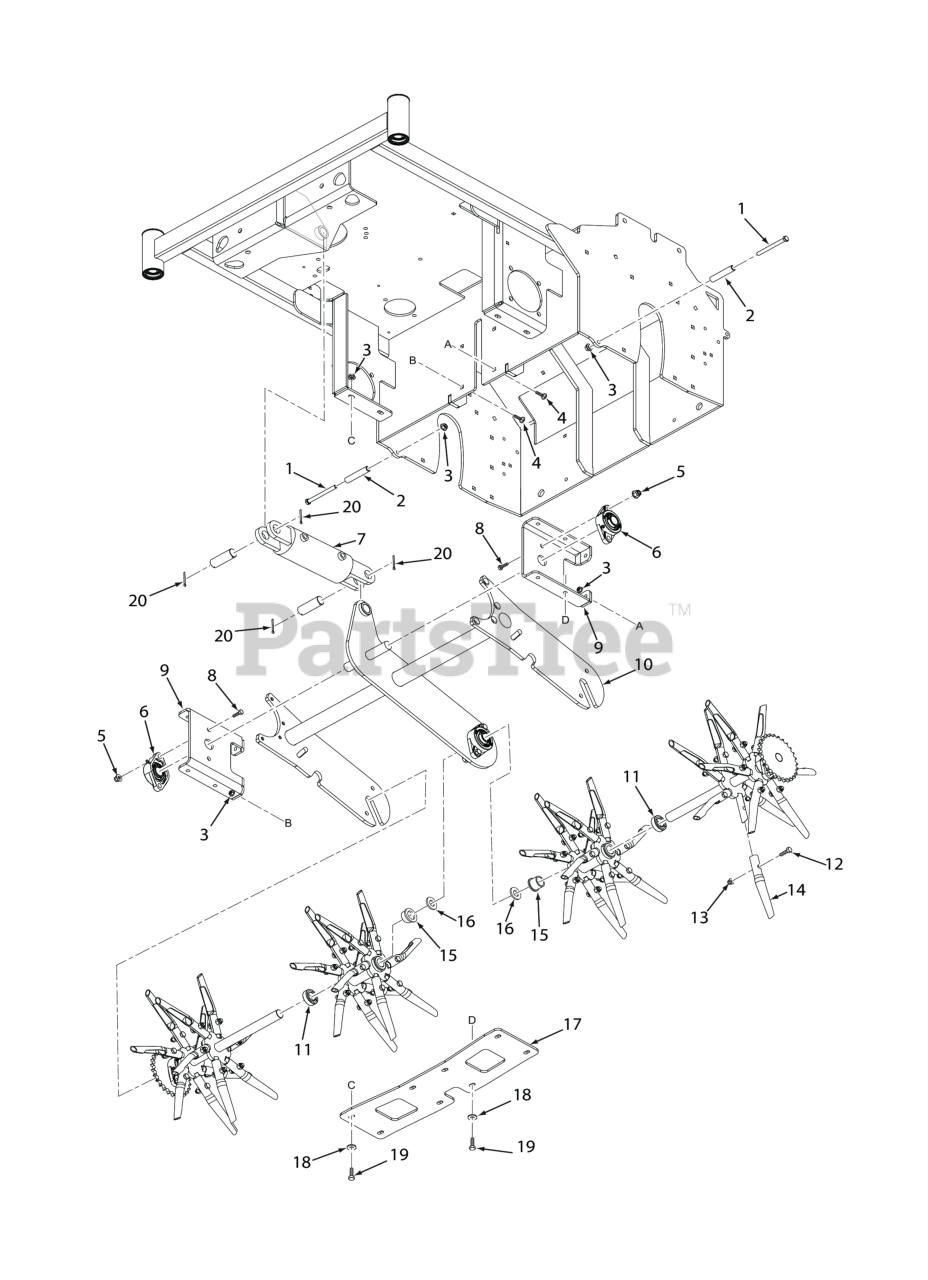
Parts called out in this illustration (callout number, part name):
1	Bolt, Hex Head 3/8-16 x 4.00
2	Spacer, Wheel Mount
3	NUT, 3/8-16 SERRATED FLANGE HEX HEAD
4	SHORT SQ. NECK CARRIAGE BOLT, 3/8-16 X 1-1/4"
5	HEX NUT, 7/16-14 SERRATED FLANGE
6	Bearing, 1" Flange
7	Cylinder, 3.00 Bore x 4.00 Stroke
8	Bolt, Hex Head 7/16-20 x 1"
9	Pivot Arm Mnt
10	Pivot Arm Wlmt
11	Clamp Collar, 1.25 Bore 2 Piece
12	Bolt, Hex Head 3/8-16 x 1-1/2" B&S 32BV
13	HEX NUT, ELASTIC STOP LOCK, 3/8-16
15	Bushing, 1" ID Oilite
16	Flatwasher, 1" (1.062 x 1.75 x .10)
17	Brace, Wheelmotors
18	Flatwasher, 3/8" Special (.391 x .938 x .105)
19	HH BOLT, 3/8-16 X 1.0 PL STL
20	Pin, Cotter 9/16" x 1-1/2"
